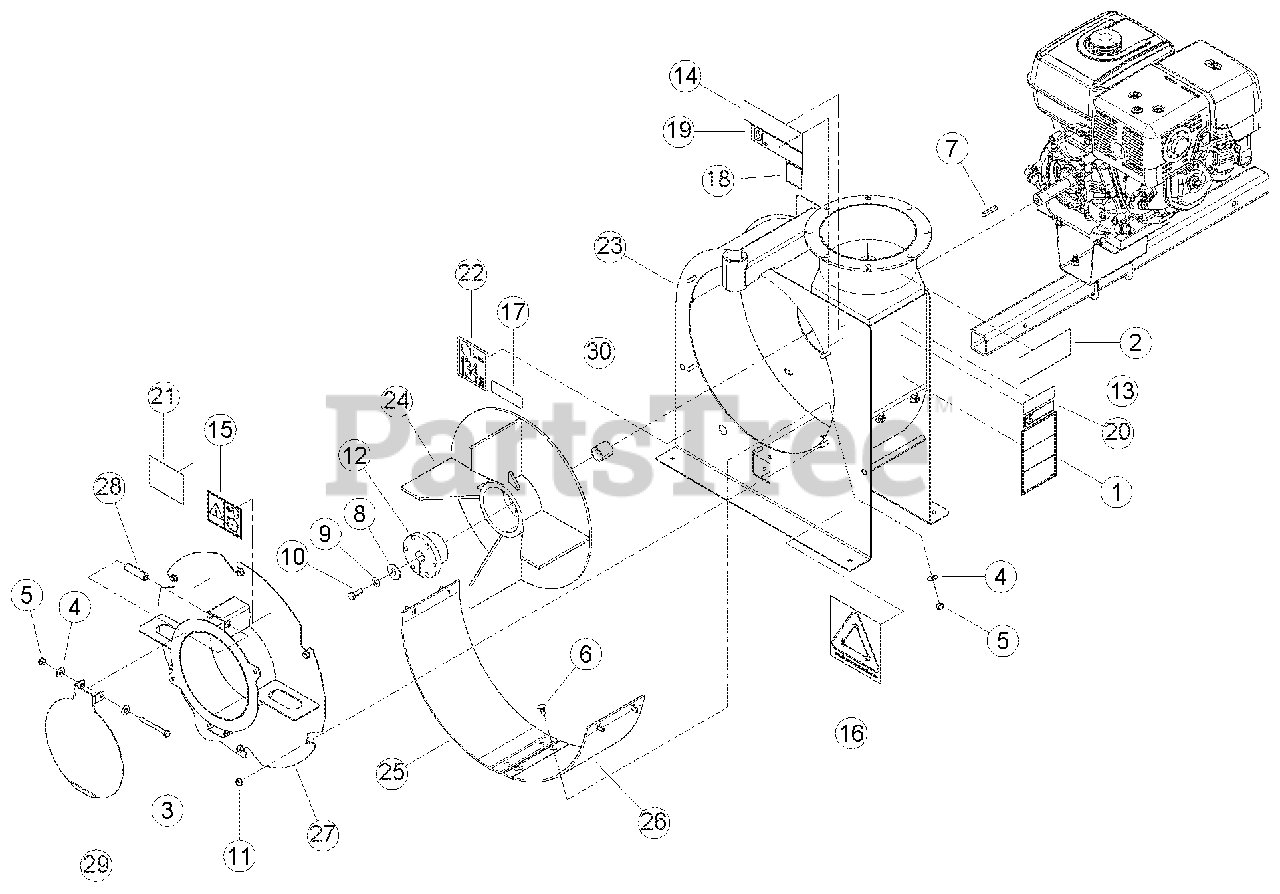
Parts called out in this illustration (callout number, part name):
1	OPERATING INSTRUCTIONS ISO
2	V, MUTILINGUAL MANUAL
3	BOLT, 5/16 X 3 HEX HD GR5 ZP
4	WASHER, 5/16 FLAT ZP
5	NUT, 5/16 NE NYLOCK ZP
6	BOLT, 5/16 X 3/4 CRG GR5 NC ZP
7	KEY, 1/4 SQUARE X 1-1/2 LONG PLAIN
8	WASHER, 1/2 GR8 USS ZP
9	WASHER, 3/8 GR8 USS ZP
10	BOLT, 3/8 X 1 HHCS NF GR8 ZP
11	NUT, 5/16 FLANGE TOPLOCK
12	BUSHING, 1" SK
13	DECAL, SERIAL NUMBER
14	DECAL, ECHO BEARCAT 6.82 X 1.90
15	DECAL, INSTRUCTION ISO
16	DECAL, COLLECT IT
17	DECAL, ATLANTIC BRIDGE LTD INFO
18	DECAL, ECHO BEARCAT QR CODE
19	DECAL, MODEL DL8390
20	DECAL, DL8390 INFO
21	DECAL, INSTRUCTION ISO
22	DECAL, 134 DB
23	WELDMENT, FAN HOUSING
24	WELDMENT, FAN
25	LINER, WEAR
26	LINER, WEAR
27	WELDMENT, VACUUM INTAKE
28	SPACER, 5/8 OD X 11 GA X 2.13
29	SHIELD, INTAKE
30	SPACER, 1-1/4 OD X 11 GA. X 1.25
